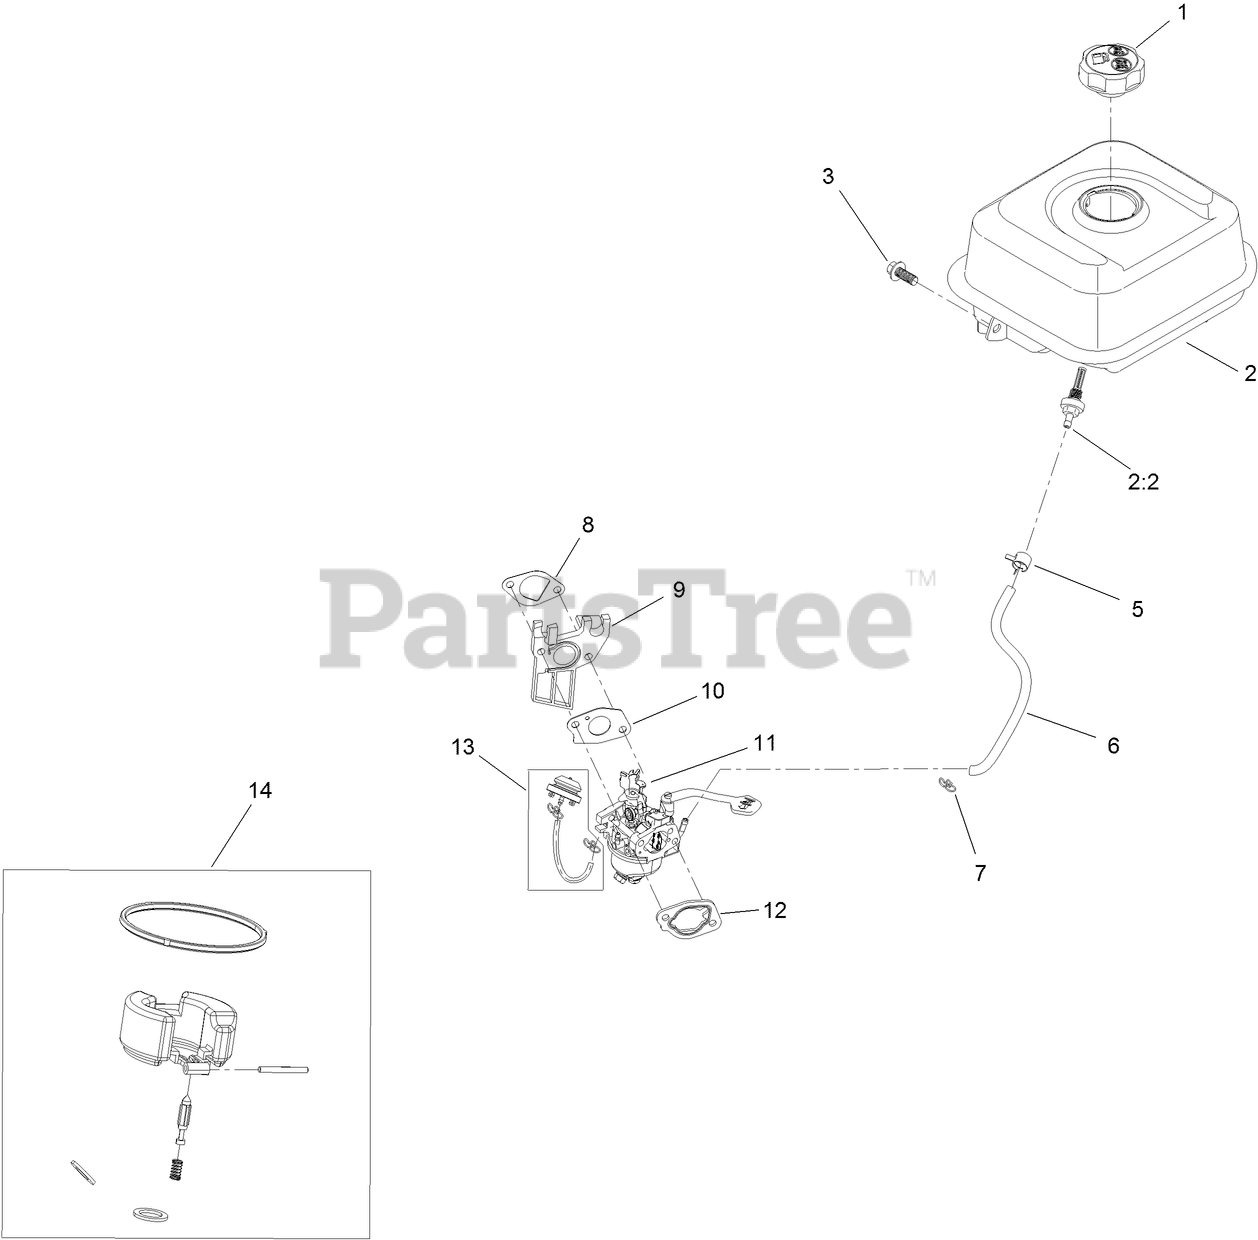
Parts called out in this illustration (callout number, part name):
1	CAP-FUEL
2	FUEL TANK AND FILTER ASM
2:2	FILTER-FUEL
3	SCREW-HHF
5	CLAMP-HOSE
6	HOSE-FUEL
7	CLAMP-HOSE
8	GASKET-CARBURETOR
9	INSULATOR-CARBURETOR
10	GASKET-CARBURETOR
11	CARBURETOR ASM
12	GASKET-CARBURETOR
13	PRIMER KIT
14	INTERNAL CARB SERVICE KIT
